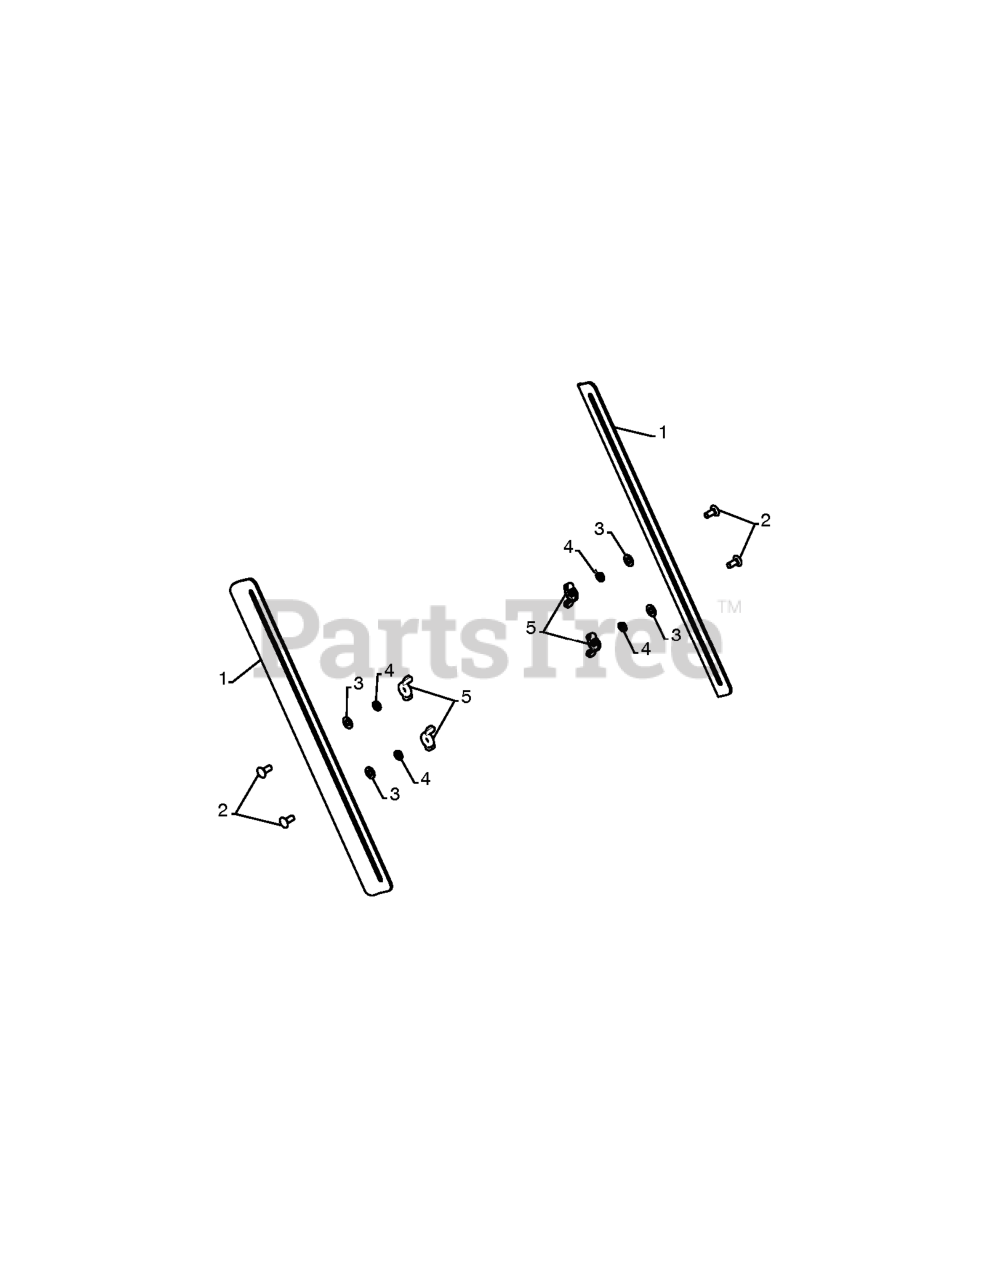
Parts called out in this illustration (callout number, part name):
1	DRIFT CUTTER BAR
2	BOLT
3	WASHER, NYLON FRICTION
4	WASHER.LOCK.HVY.HLCL.SPR.5/16
5	NUT WING PM
